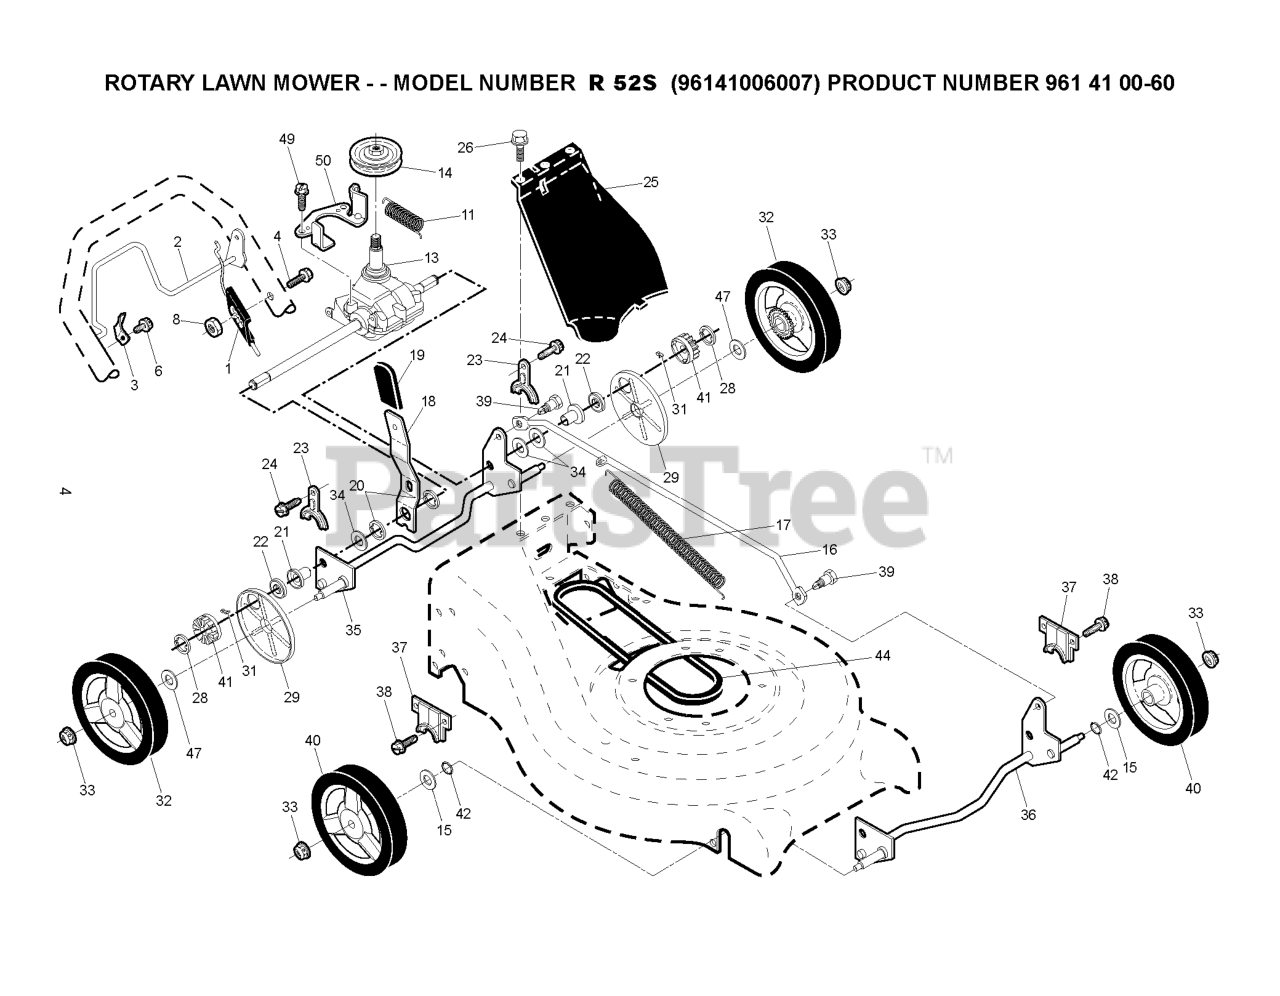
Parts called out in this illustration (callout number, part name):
3	DOWNSTOP BRACKET
8	NUT.HEX.FLANGE.1/4
13	TRANSMISSION.21.RWGD
14	PULLEY.RGD.SS.3.25OP
15	WASHER.FLAT.1/2
16	ROD.CONNECTING.SPT.BLACK
17	SPRING EXTENSION
18	SPRING.SELECTOR.
19	KNOB.EXT.ERGO.BLACK
21	BEARING SUPPORT
22	BEARING
23	BRACKET
24	SCREW 14-20 X 5/8
25	COVER.DRIVE.21.RWGD.MO
28	E-RING 7/16 RE
29	COVER.DUST.WHEEL
31	PAWL, DRIVE
32	WHEEL & TIRE ASSY, REAR
33	NUT.HEX.FLANGE.3/8-16.LO(3 2)
35	SHAFT ASSY REAR
36	SHAFT ASSY, FRONT
37	RETAINER.FRONT.SHAFT
39	SHOULDER BOLT SEMI GIMLET PT.
40	WHEEL & TIRES ASSY, FRONT
41	PINIION.14.TOOTH.RGD
42	O-RING..070X.487.NEOPRENE
44	RP.BELT.DRIVE.RGD.SS.WALK
47	WASHER FLUT
50	BRACKET.BELT.KEEPE/AUT*SUBS/2*
